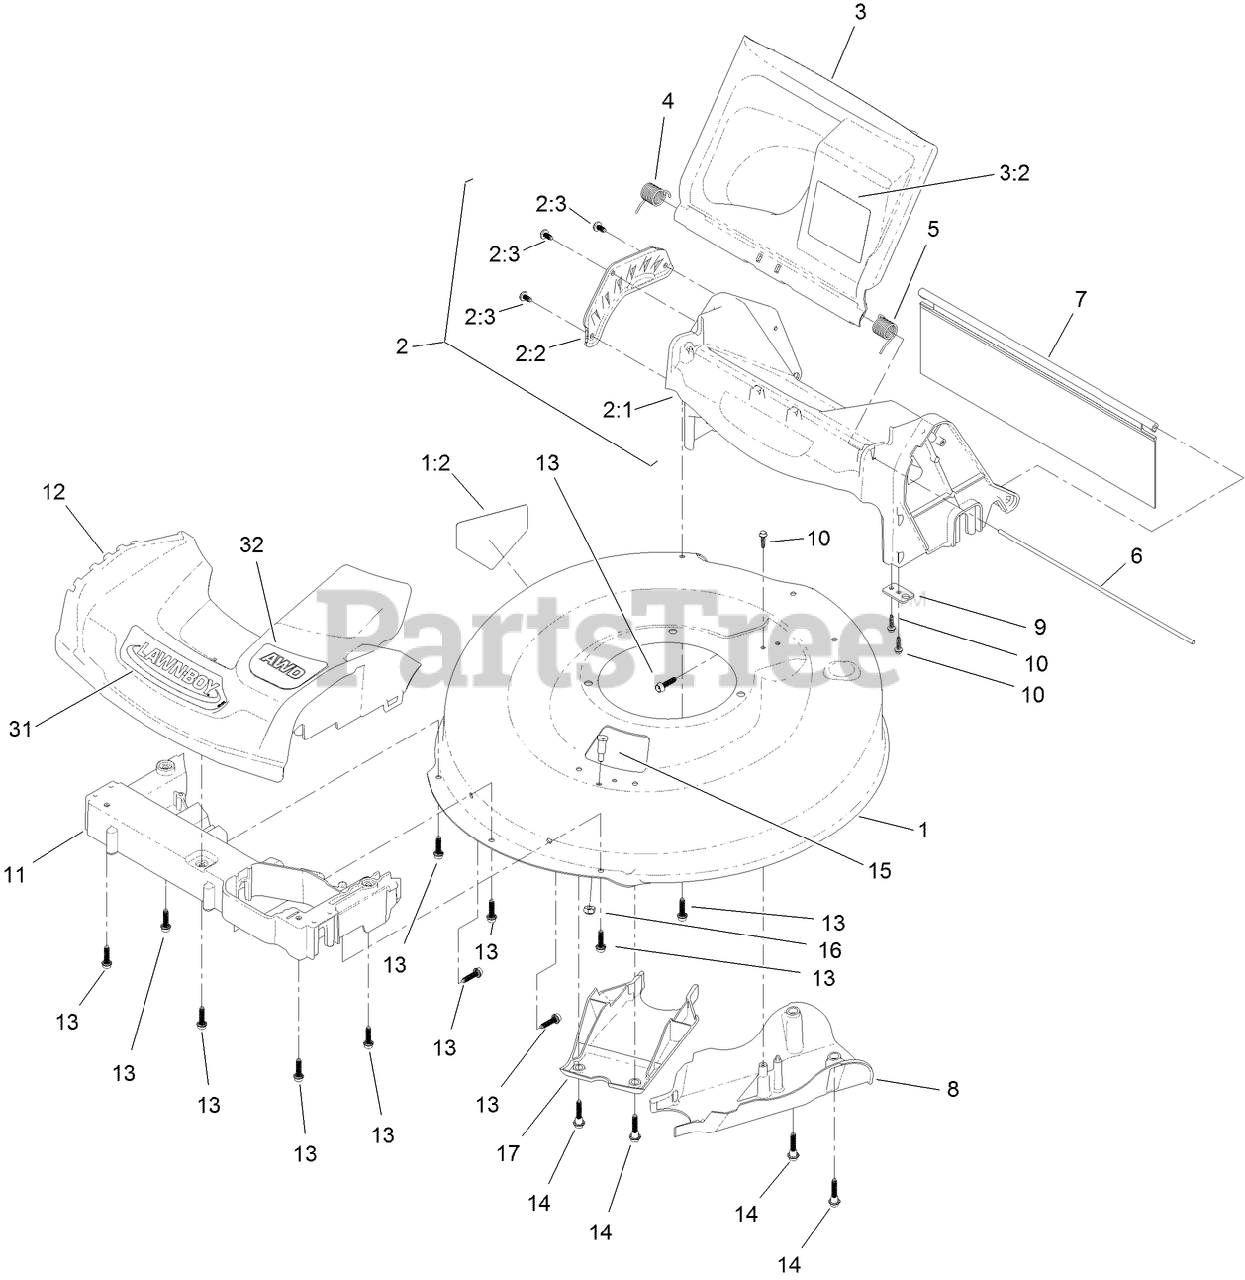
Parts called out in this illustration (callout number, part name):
1	HOUSING ASM
1:2	DECAL-DANGER
2	CHUTE ASM
2:1	CHUTE
2:3	SCREW-PLASTIC TPH
3	REAR DEFLECTOR ASM
3:2	DECAL-WARNING
4	SPRING-TORSION
5	SPRING-TORSION
7	SHIELD-TRAILING
8	COVER-BELT
9	BRACKET-CABLE
10	SCREW-HWH
11	MOUNT-BUMPER
13	SCREW-FLANGE, PLASTIC
14	SCREW-SHOULDER, HHF
15	BOLT-SHOULDER
16	NUT-LOCK, NI
17	COVER-BELT, FRONT
31	DECAL-DECK
32	DECAL-COVER
